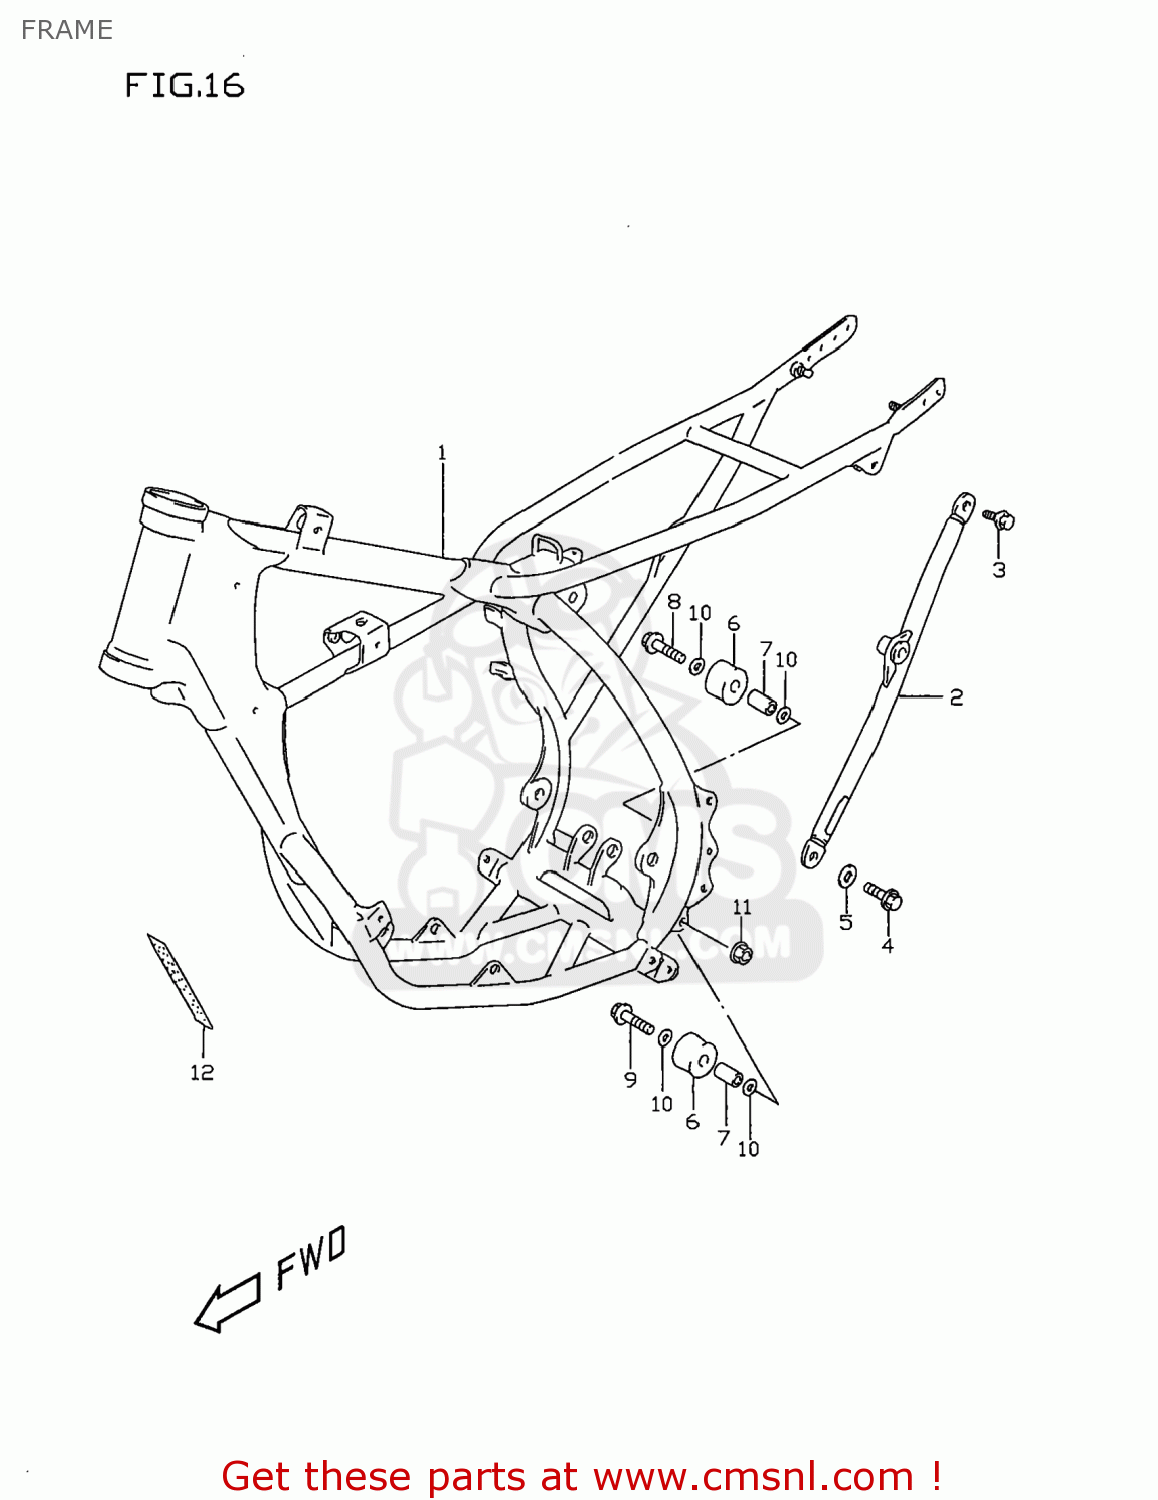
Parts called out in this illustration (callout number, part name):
1	FRAME
2	TUBE,FRAME SIDE(CHARCOAL)
3	BOLT(8X22)
4	BOLT(8X16)
5	WASHER
6	ROLLER,CHAIN CONTROL
7	SPACER(8.6X12X25.5)
8	BOLT(8X38)
9	BOLT
10	WASHER
11	NUT
12	PLATE,WARNING
